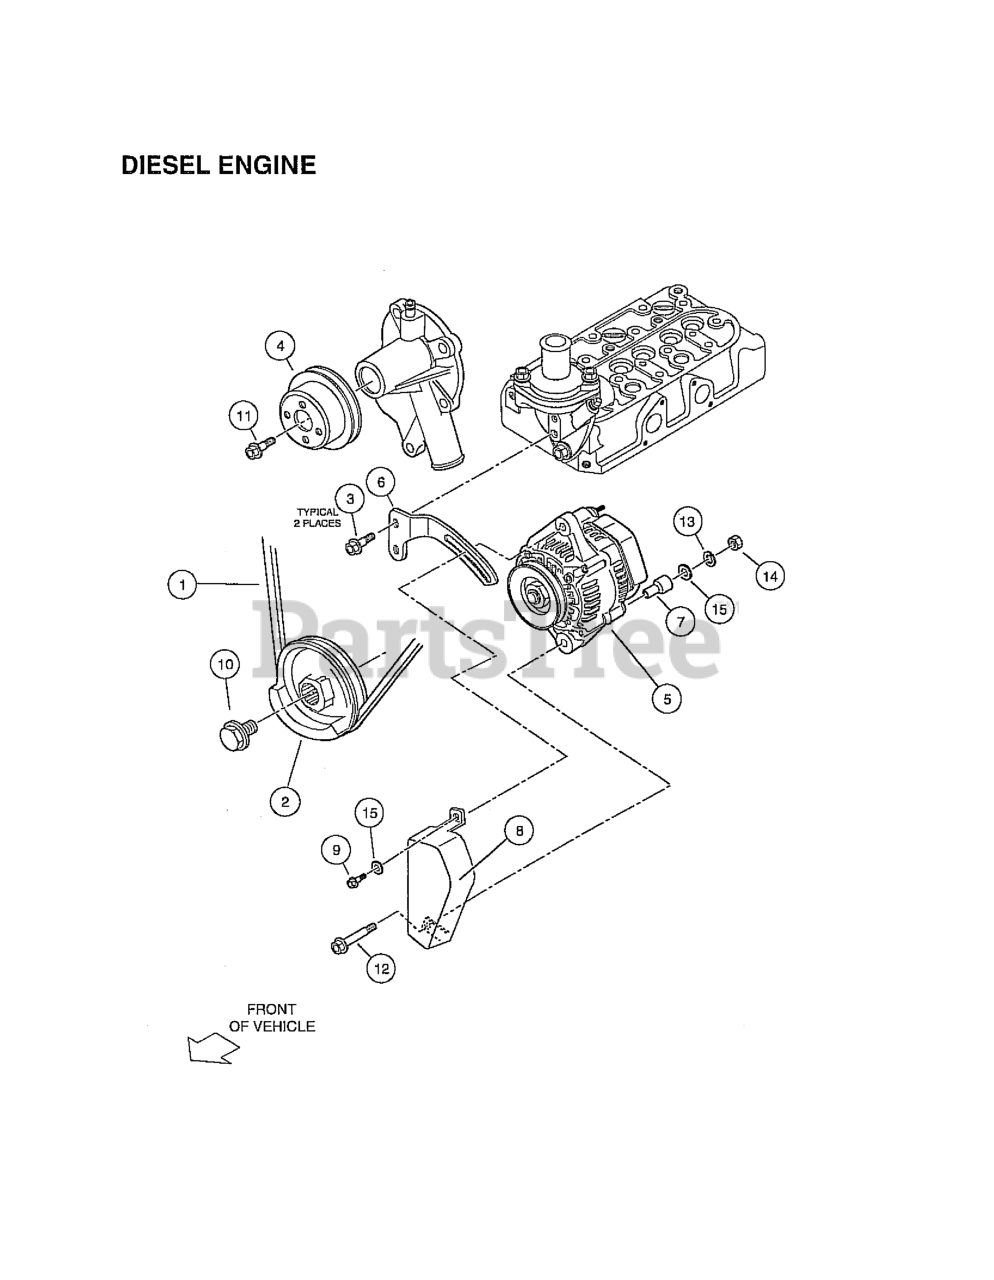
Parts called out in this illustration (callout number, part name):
2	PULLEY, FAN DRIVE
3	BOLT, M6X1X20
4	PULLEY, WATER PUMP
5	ALTERNATOR ASSY, D722 40 AMP
6	STAY, ALTERNATOR ASSY, D722
7	COLLAR, ALTERNATOR ASSY, D722
8	COVER, ALTERNATOR ASSY, D722
9	BOLT, ALT, D722, ADJUSTER
10	BOLT, ALT, D722, DRIVE PULLEY
11	BOLT, D722, DRIVE PULLEY
12	BOLT-ALT-LOWER
13	WASHER-ALT-LOCK
14	NUT-ALT-LOWER
15	WASHER-ALT-UPPER
